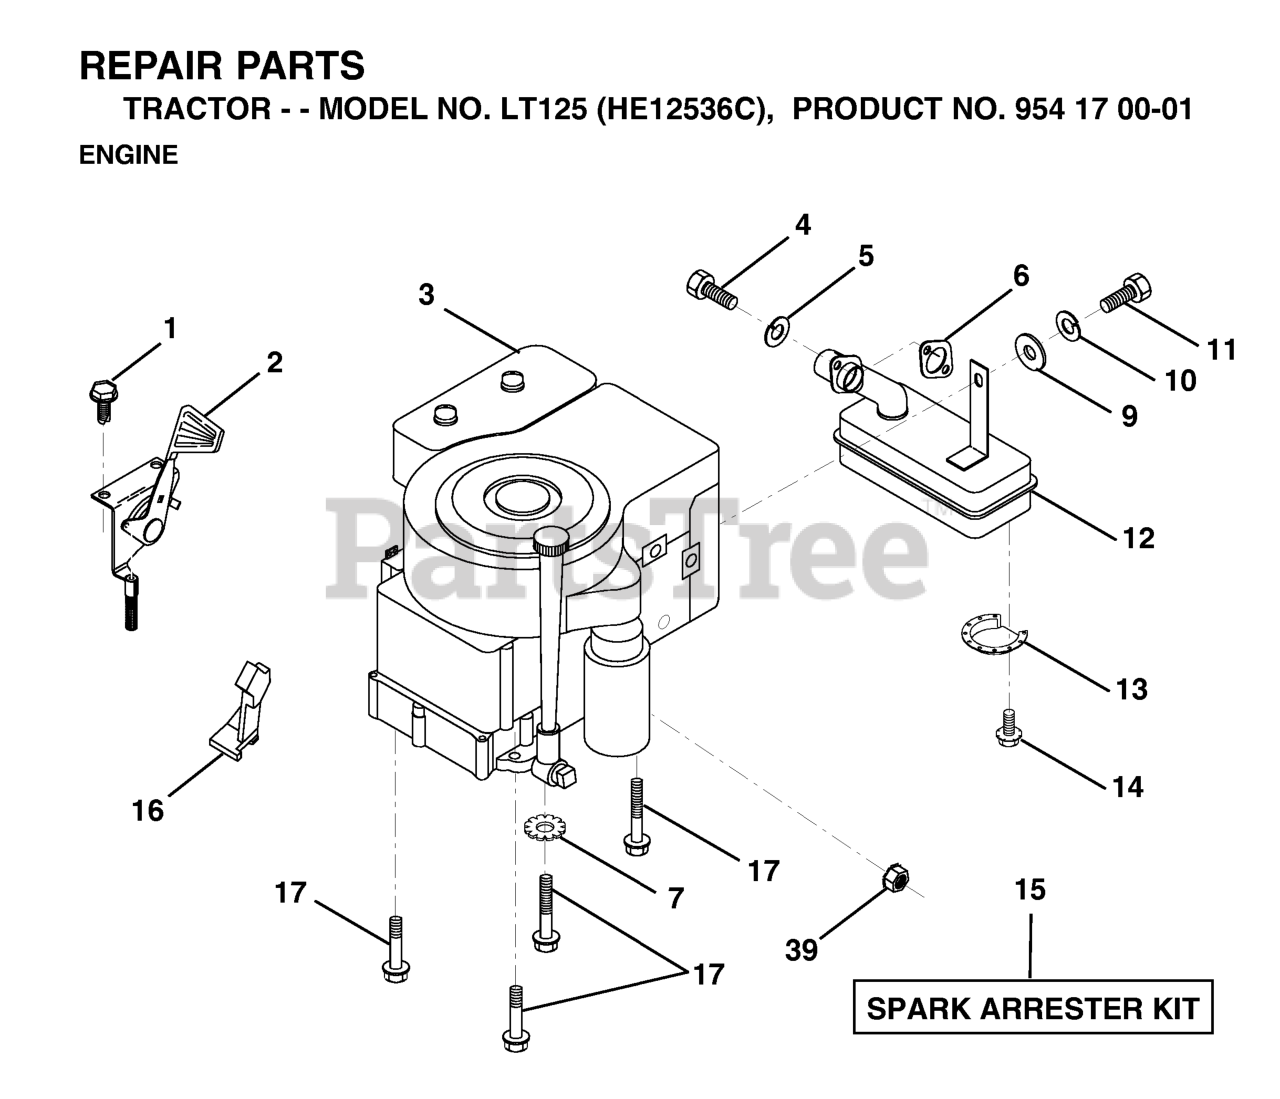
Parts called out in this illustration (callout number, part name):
2	CONTROL.TH/CH.RH.BLK.FLG.EEC
4	SCREW
5	WASHER.LOCK.HVY.HLCL.SPR.5/16
6	GASKET.ENG.1.313 ID.TIN PLATED
7	LOCKWASHER
9	WASHER
10	LOCKWASHER
12	MUFFLER.SINGLE.B&S.12HP
13	DEFL MUFFLER LTV
14	SCREW
15	KIT.SPARK ARRESTOR 794945 B&S
16	STOP THROTTLE
17	SCREW LT
39	NUT FLANGE 1/4-20 STARTER NUT
